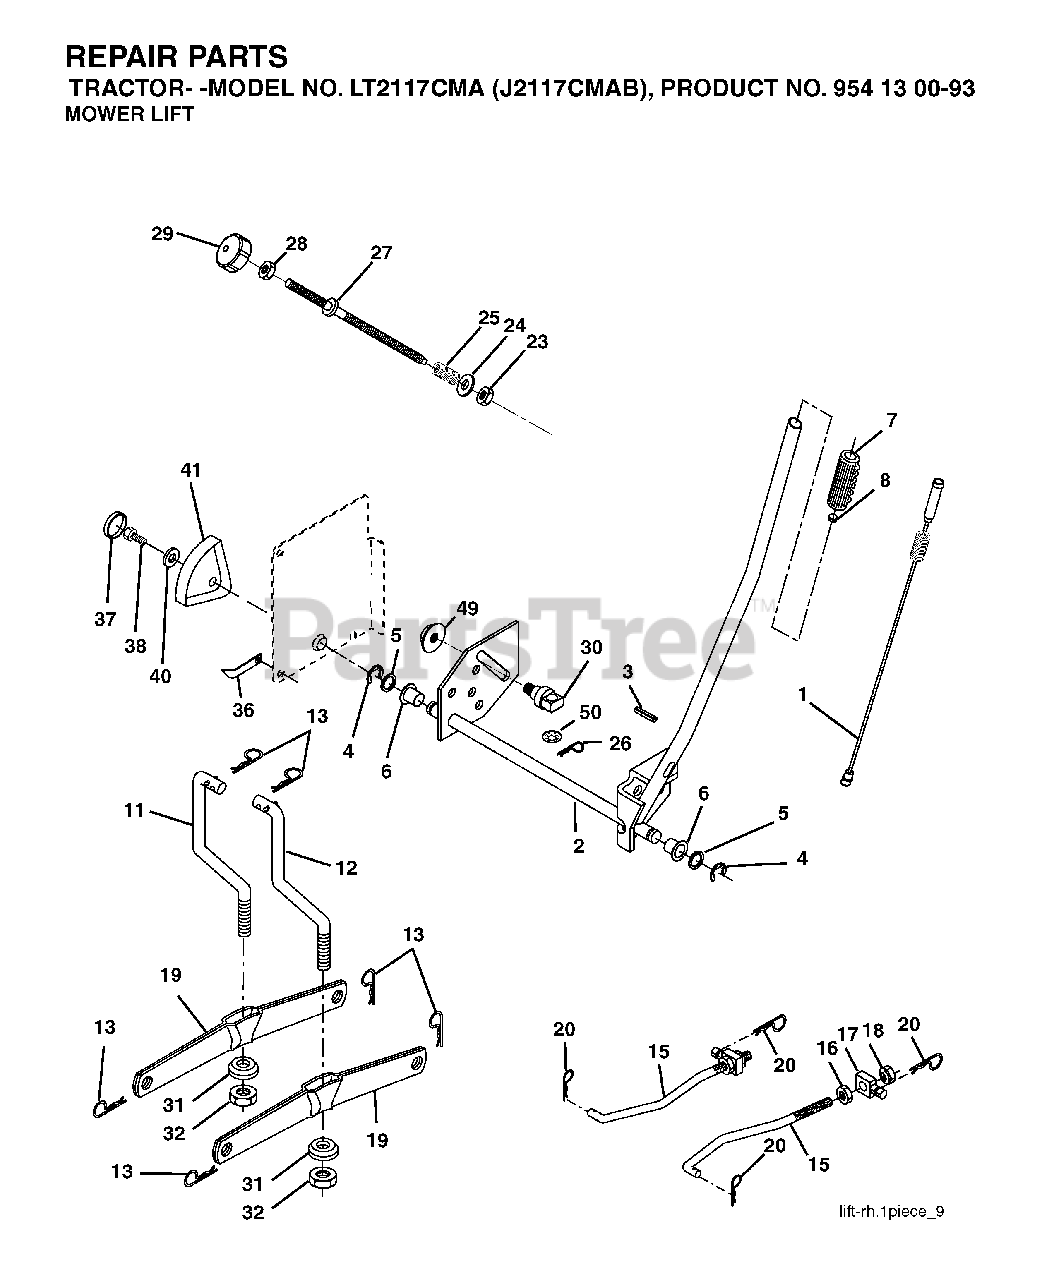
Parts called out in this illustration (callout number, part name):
1	WIRE ASM INNER W/ PLUNGER LT
2	SHAFT ASM R HANDLE
3	PIN GROOVE
4	RETAINING RING LT
6	BEARING.NYLON
7	GRIP HANDLE
8	PLUNGER BUT KIT
11	LINK
12	LINK
13	RETAINER-SPRNG RB
15	LINK.SUSPENSION.FRONT
16	NUT
18	NUT
19	ARM.REAR.SUSPENSION
20	SPRING RETAINER
25	SPRING**
26	RETAINER CLIP
27	ROD ADJ LIFT
28	NUT
29	KNOB INF 3/8-16
31	BEARING.PIVOT.LIFT
32	NUT CROWNLOCK 3/8-24
36	POINTER, HEIGHT INDICATOR
37	PLUG,HOLE
38	SCREW 5/16-18X1
41	HEIGHT INDICATOR
49	NUT
50	NUT PUSH M
